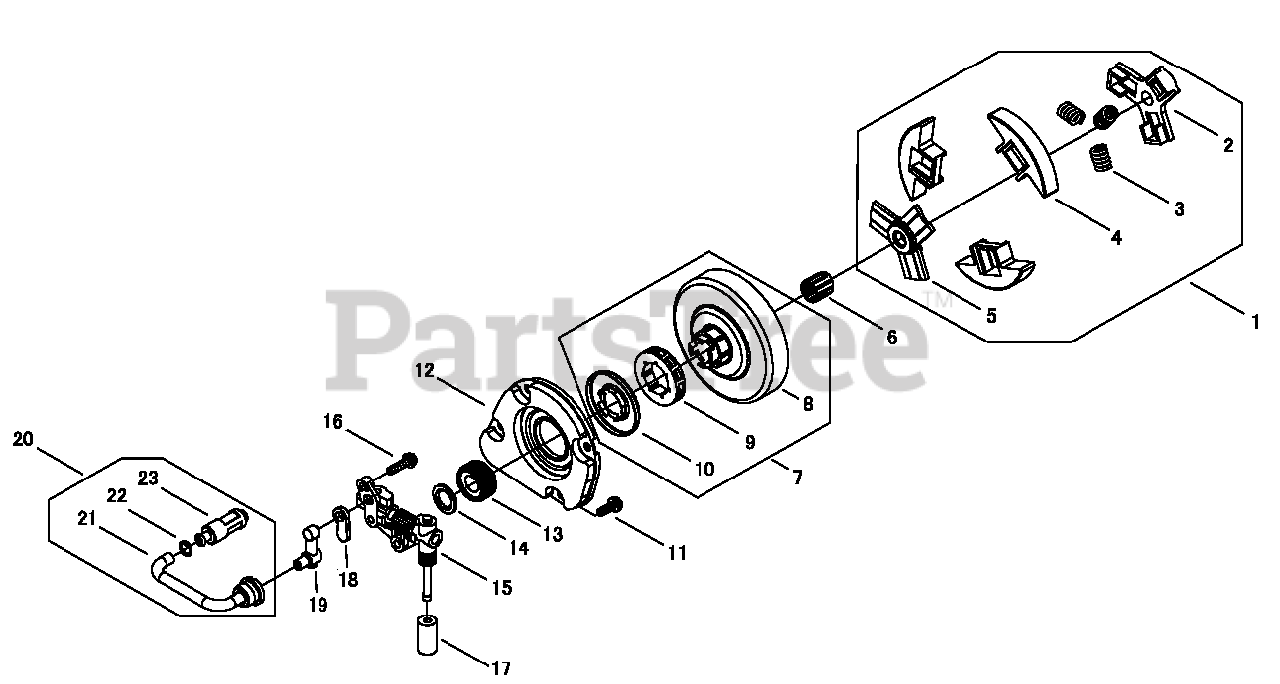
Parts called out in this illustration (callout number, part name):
1	CLUTCH ASSY
2	HUB, CLUTCH - OUTER
3	SPRING, CLUTCH
4	SHOE, CLUTCH
5	HUB, CLUTCH - INNER
6	BEARING, NEEDLE
7	DRUM, CLUTCH
8	DRUM, CLUTCH
9	SPROCKET, RIM
10	COVER
11	SCREW
12	PUMP COVER SUB ASSY
13	GEAR
14	PLATE, THRUST
15	OIL PUMP ASSY
16	SCREW - 4X16
17	FILTER
18	GASKET, PUMP
19	CONNECTOR, PIPE
20	OIL PIPE ASSY
21	PIPE - OIL
22	CLIP
23	FILTER, OIL
